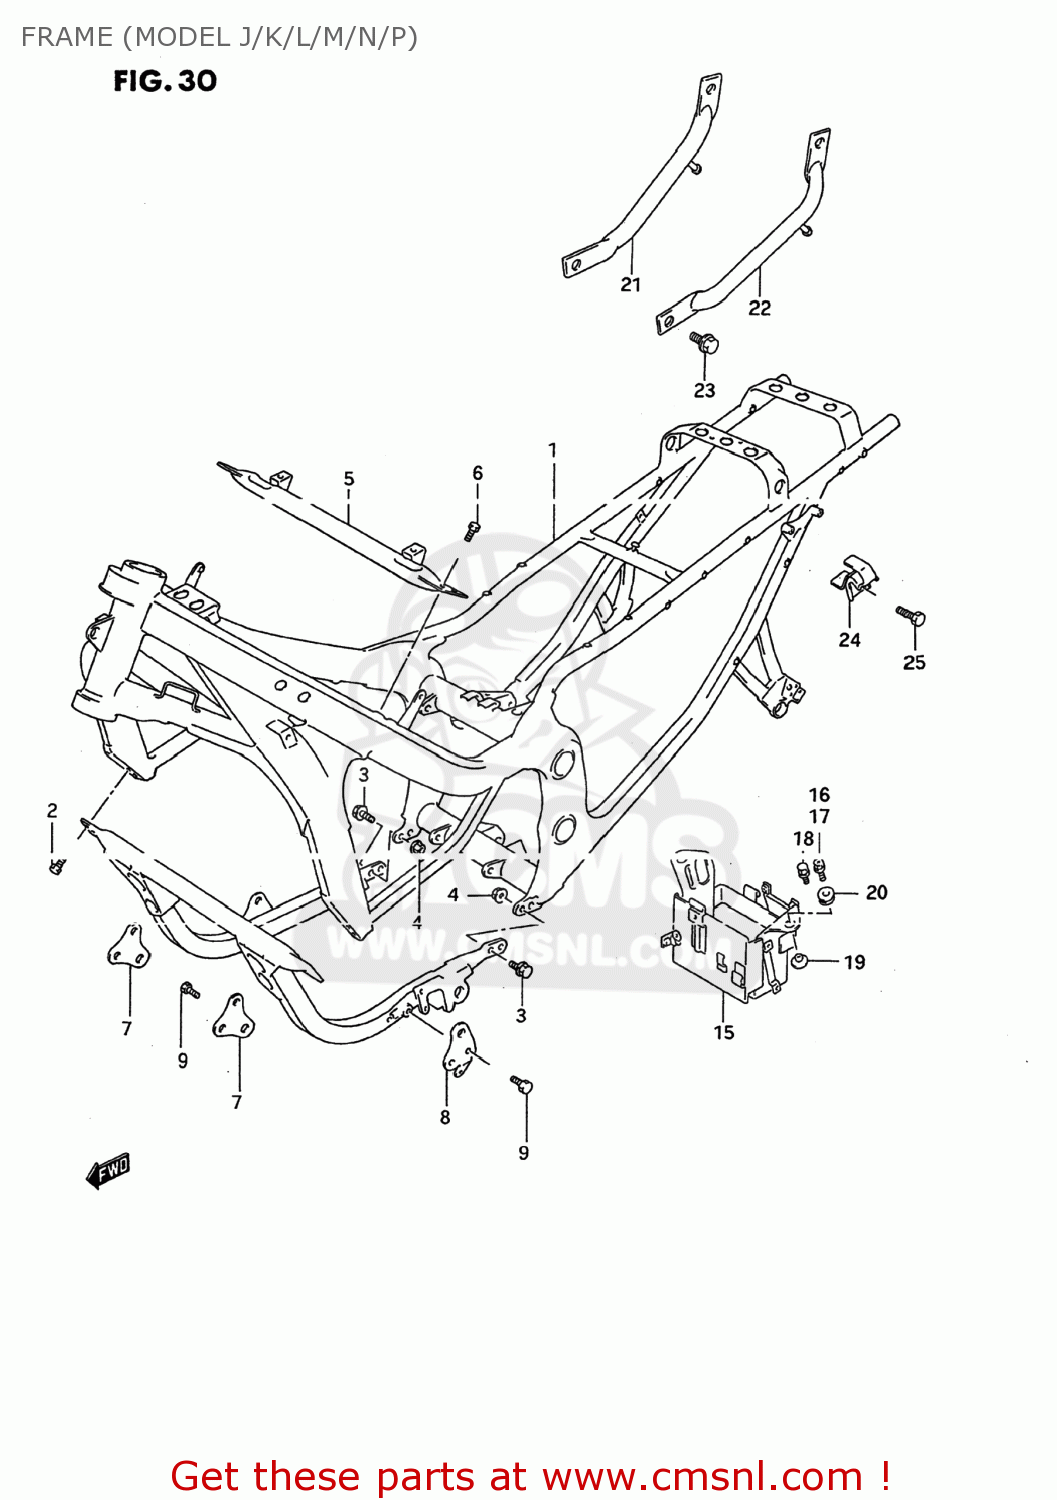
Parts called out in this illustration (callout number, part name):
1	FRAME
2	TUBE,FRAME
3	BOLT
4	WASHER,LOCK
5	BOLT
6	BOLT
7	NUT
8	TUBE,FRAME
9	BOLT
10	WASHER,LOCK,8.
11	PLATE,ENG MTG NO.1
12	PLATE,ENGINE MOUNTING
13	BOLT
14	WASHER,LOCK,8.
15	HOLDER,BATTERY
16	SCREW(6X30)
17	WASHER,LOCK
18	BOLT L:30
19	PLATE,BATTERY HOLDER
20	CUSHION
21	GRIP,REAR,RIGHT
22	GRIP,REAR
23	BOLT, LOWER
24	HOLDER,HELMET
25	BOLT
